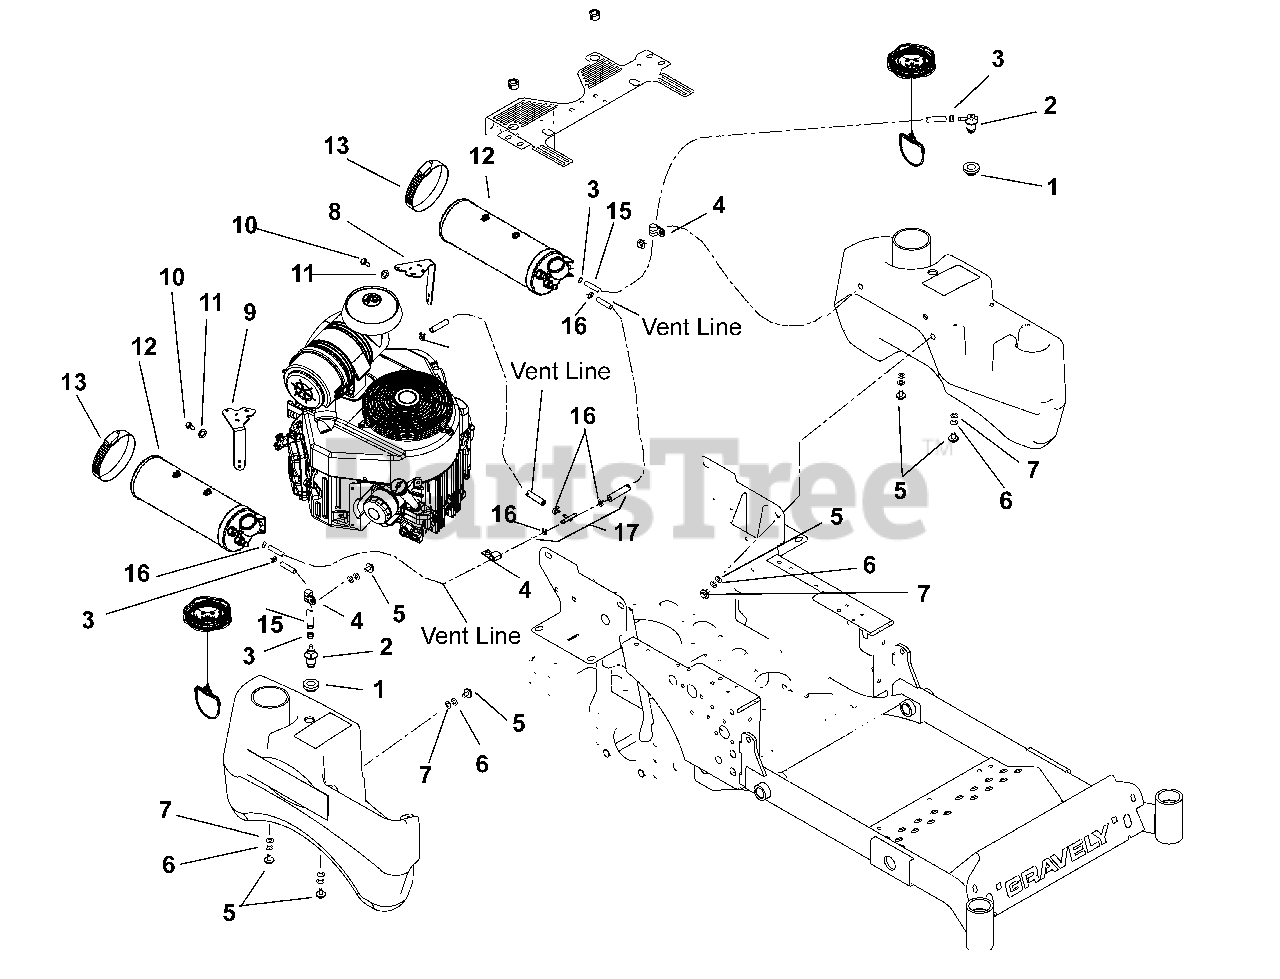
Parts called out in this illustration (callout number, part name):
2	Valve
3	Hose, Clamp
5	Bolt, .31-18 x .62
6	Washer, Locking .31 x .078 Regular
7	Washer, Flat Steel .38 x .875 x .083
8	Bracket, CE Canister Mounting Left Hand
9	Bracket, CE Canister Mounting Right Hand
10	Bolt, Hex M8-1.25 x 20mm
11	Washer, Lock.31 x .078 Reg
12	Canister, Carbon 400 cc CARB
13	Clamp, Hose 2.3/3.2 SS #44
14	T-Clip .38-.50
15	Hose, .25 Low-PERM Bulk Gas 21.0"
16	Clamp, Hose Spring .188
17	Assembly, Compact Pro Vapor CARB (Includes items 16 and vent lines)
